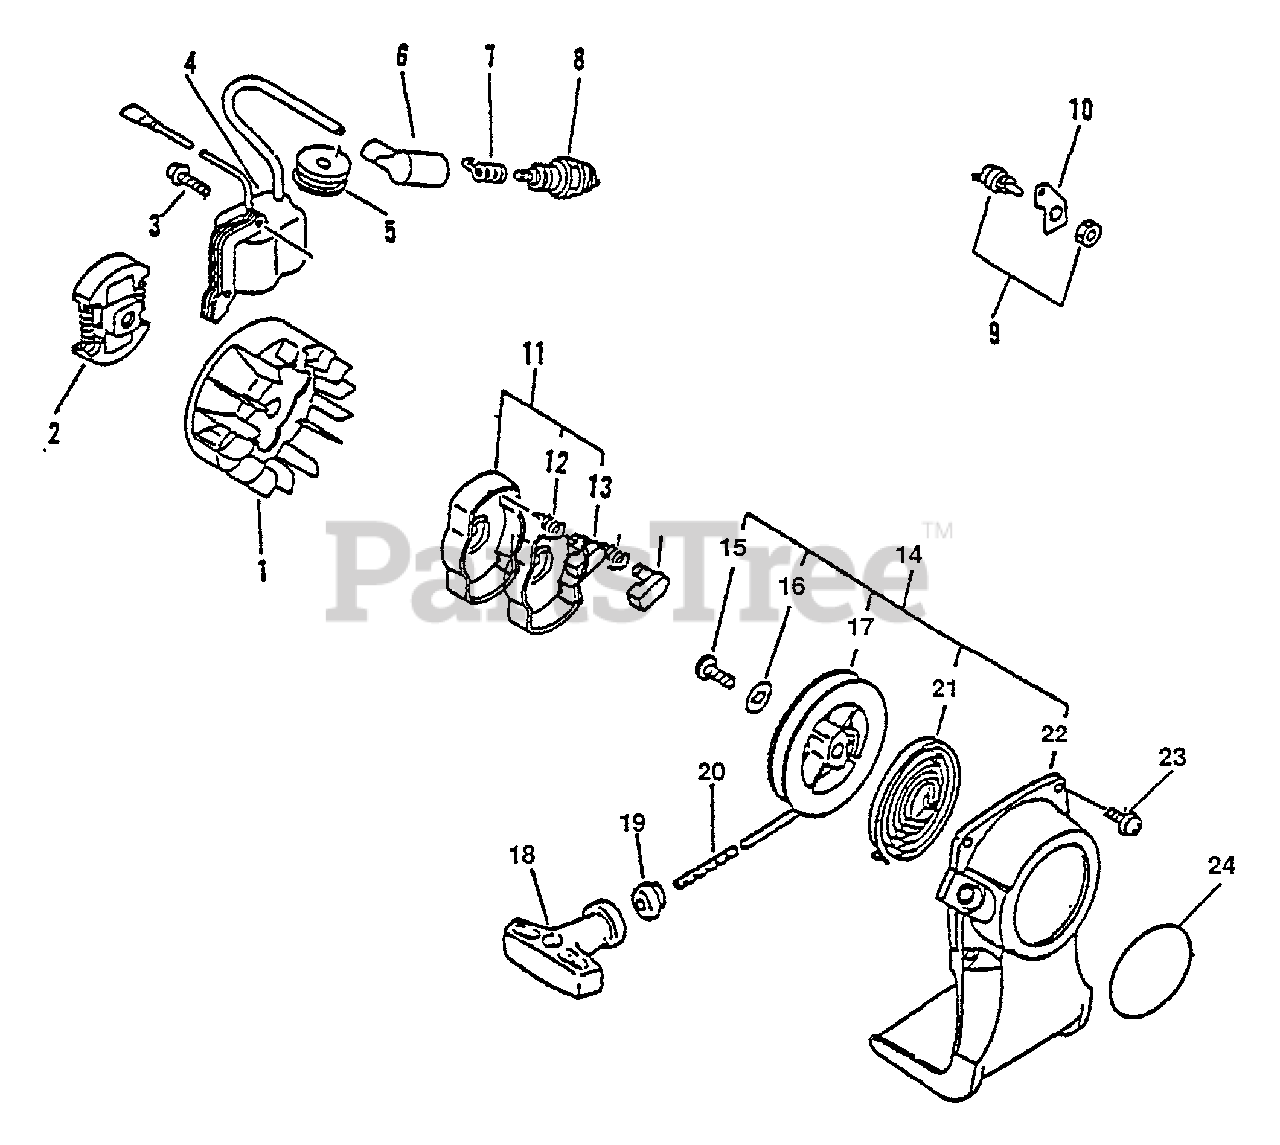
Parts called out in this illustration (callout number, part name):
1	FLYWHEEL
2	CLUTCH ASSY
3	SCREW 4×22
4	COIL, IGNITION
6	CAP, SPARK PLUG
7	TERMINAL, SPARK PLUG
8	SPARK PLUG - BPM7A
9	SWITCH, ON-OFF
10	BRACKET, SWITCH
11	PAWL ASSY, STARTER
12	SPRING, RETURN
13	PAWL, STARTER - BLACK
14	STARTER ASSY
15	SCREW
16	WASHER
17	REEL, ROPE
18	GRIP, STARTER
19	GUIDE, ROPE
20	ROPE, STARTER
21	SPRING, RECOIL
22	CASE, STARTER
23	SCREW 4×16
24	LABEL, ECHO
